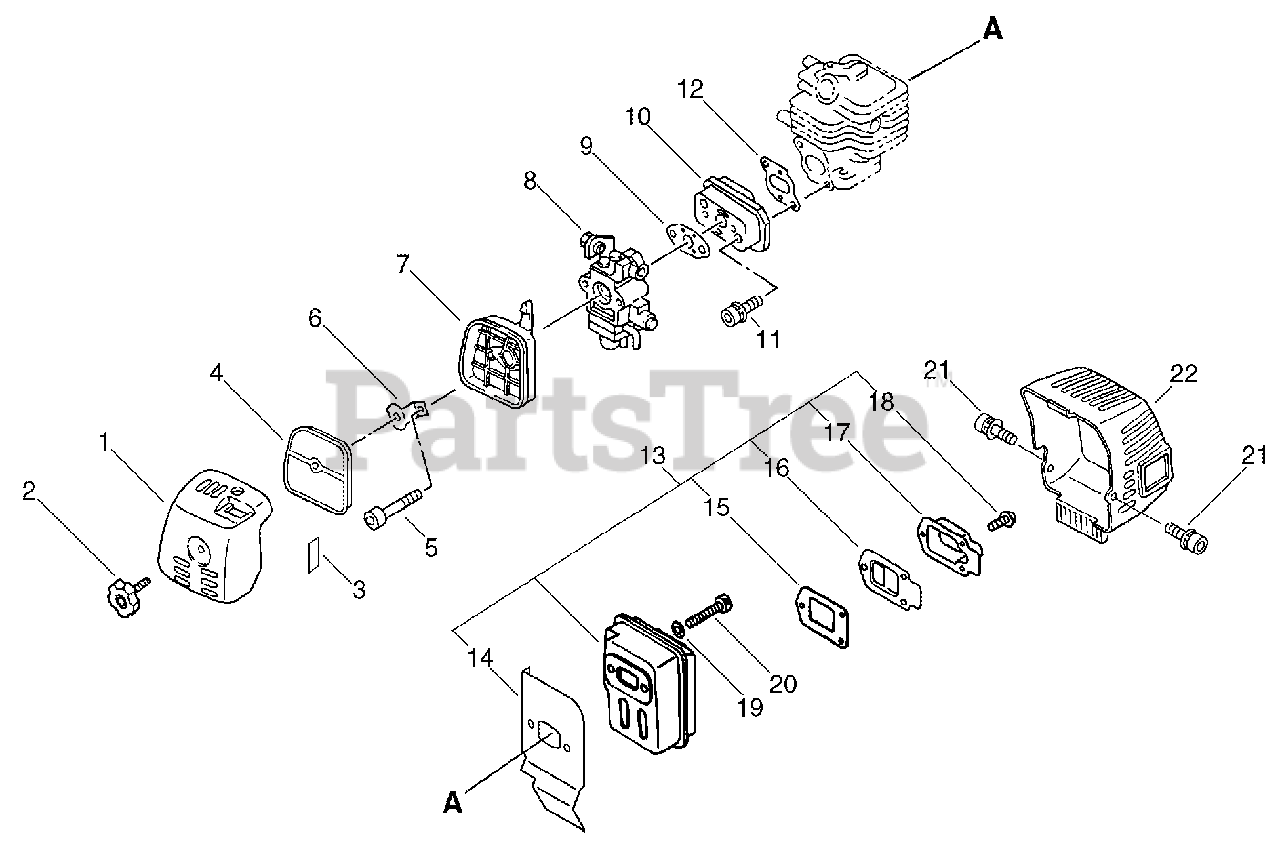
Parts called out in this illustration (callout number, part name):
1	COVER, AIR FILTER
2	THUMBSCREW
3	LABEL - CHOKE
4	FILTER, AIR - HEAVY DUTY
5	SCREW - 5X55
6	PLATE, PRVENT
7	CASE, AIR FILTER
8	CARBURETOR WYJ-192A
9	GASKET, INTAKE
10	INSULATOR, INTAKE
11	SCREW - 5X25
12	GASKET, INTAKE
13	MUFFLER ASSY
14	SHIELD, EXHAUST
15	GASKET, EXHAUST
16	GASKET, EXHAUST - INNER
17	GUIDE, EXHAUST - OUTER
18	SCREW - 4X10
19	WASHER - 5
20	SCREW - 5X55
21	SCREW - 5X12
22	COVER, MUFFLER
